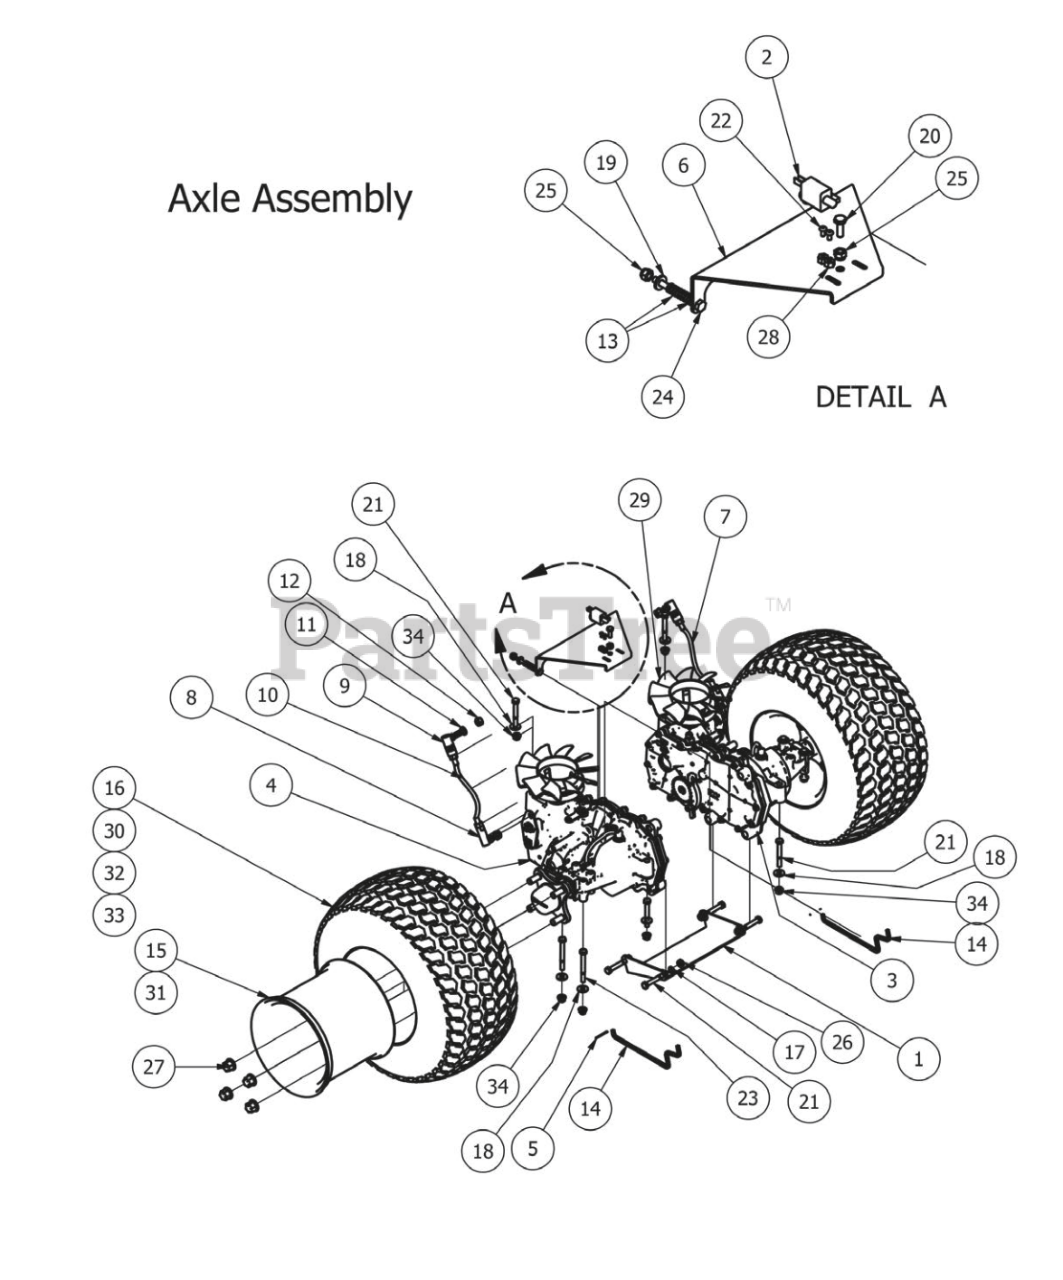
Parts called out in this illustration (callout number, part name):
1	MZ Transaxle Support (Lower)
2	Safety Switch
3	EZT - Right MZ Models
4	EZT-Left MZ Models
5	Cotter Pin-Brake bar on Mz
6	MZ Brake Lock Bracket
7	Steering linkage for Mz Left
8	3/8-24 Ball Joint
9	Quick Release Ball Joint
10	Steering linkage for Mz right
11	3/8" Lock Washer
12	3/8" Fine Threaded Jam Nut
13	Brake Spring
14	MZ Brake Release Bar
15	Rear rim for a 48in
16	18 x 9.50 8 Tire Only MZ 48" Deck only
17	5/16" Lock Washer
18	5/16" Flat Washer
19	1/4" Flat Washer
20	1/4" x 3/4" Hex Bolt
21	5/16" x 2 1/2" Bolt
22	10-24 X 5/8 BS C/S 18-8 SS
23	5/16" x 3" Hex Bolt
24	1/4-20 x2-1/2 Gr2 hex C/s zinc
25	1/4" Nylock Nut
27	Acorn Lug Nut
28	10-24 Nylon Insert Locknut
29	MZ Fan & Pulley Kit
30	42" MZ 18x 7.50-8 tire only
31	Rear rim only 42" MZ
32	18x9.50-8 48" Deck Tire and Wheel Assembly
33	18x8.50-8/8" 42" Deck Tire and Wheel Assembly
34	5/16" Nylon Flange Nut
